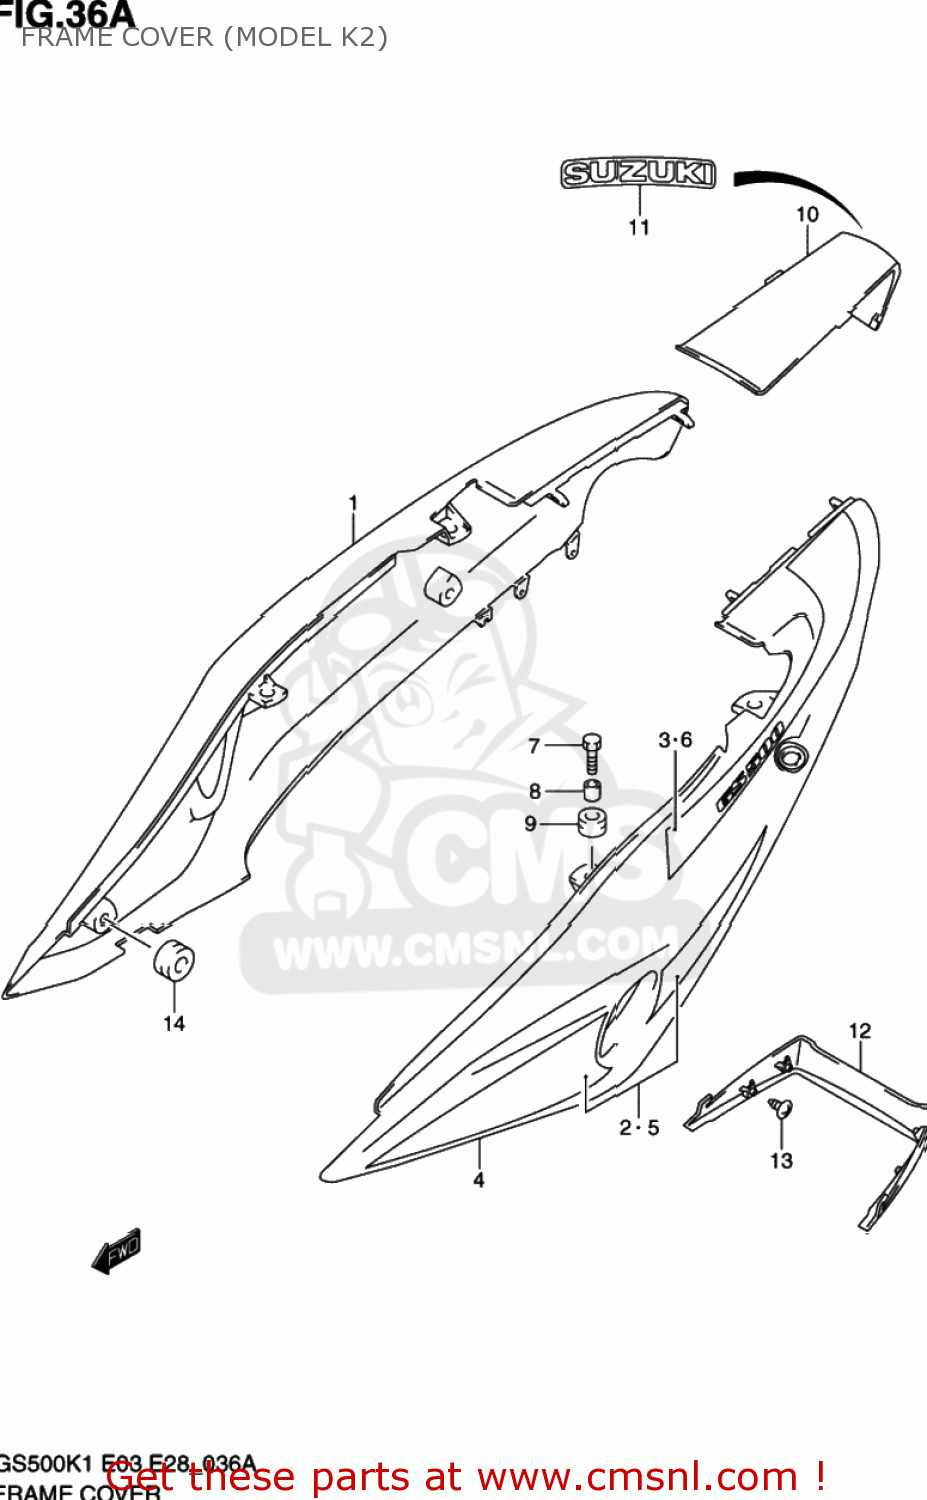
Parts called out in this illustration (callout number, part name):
1	COVER,FRAME,R(SILVER)
2	TAPE SET,FRAME COVER,R
3	TAPE,FRAME COVER,R
4	COVER,FRAME,L(SILVER)
5	TAPE SET,FRAME COVER,L
6	TAPE,FRAME COVER,L
7	BOLT(6X20)
8	SPACER(6.5X9X9)
9	CUSHION
10	COVER,FRAME CTR
11	EMBLEM(BLACK)
12	COVER, FRAME LOWER
13	SCREW
14	CUSHION
